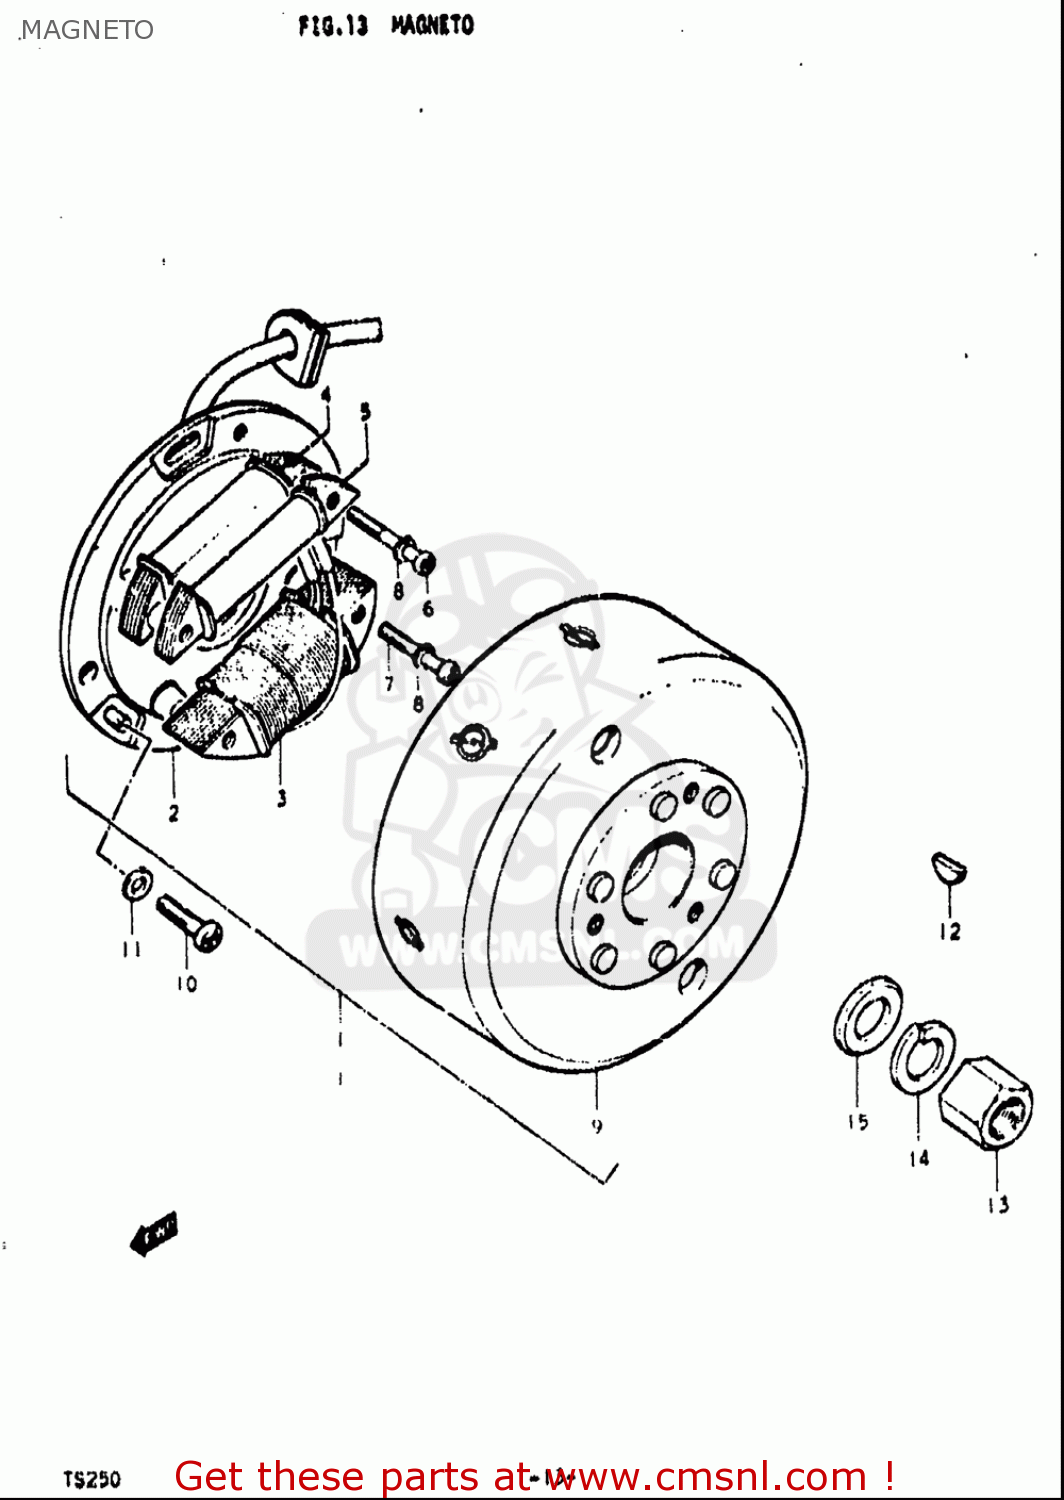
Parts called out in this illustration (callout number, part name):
6	SCREW
7	SCREW(4X30)
8	WASHER,LOCK
10	SCREW
11	WASHER
12	KEY
13	NUT
14	WASHER,LOCK
15	WASHER(14X27X3)
